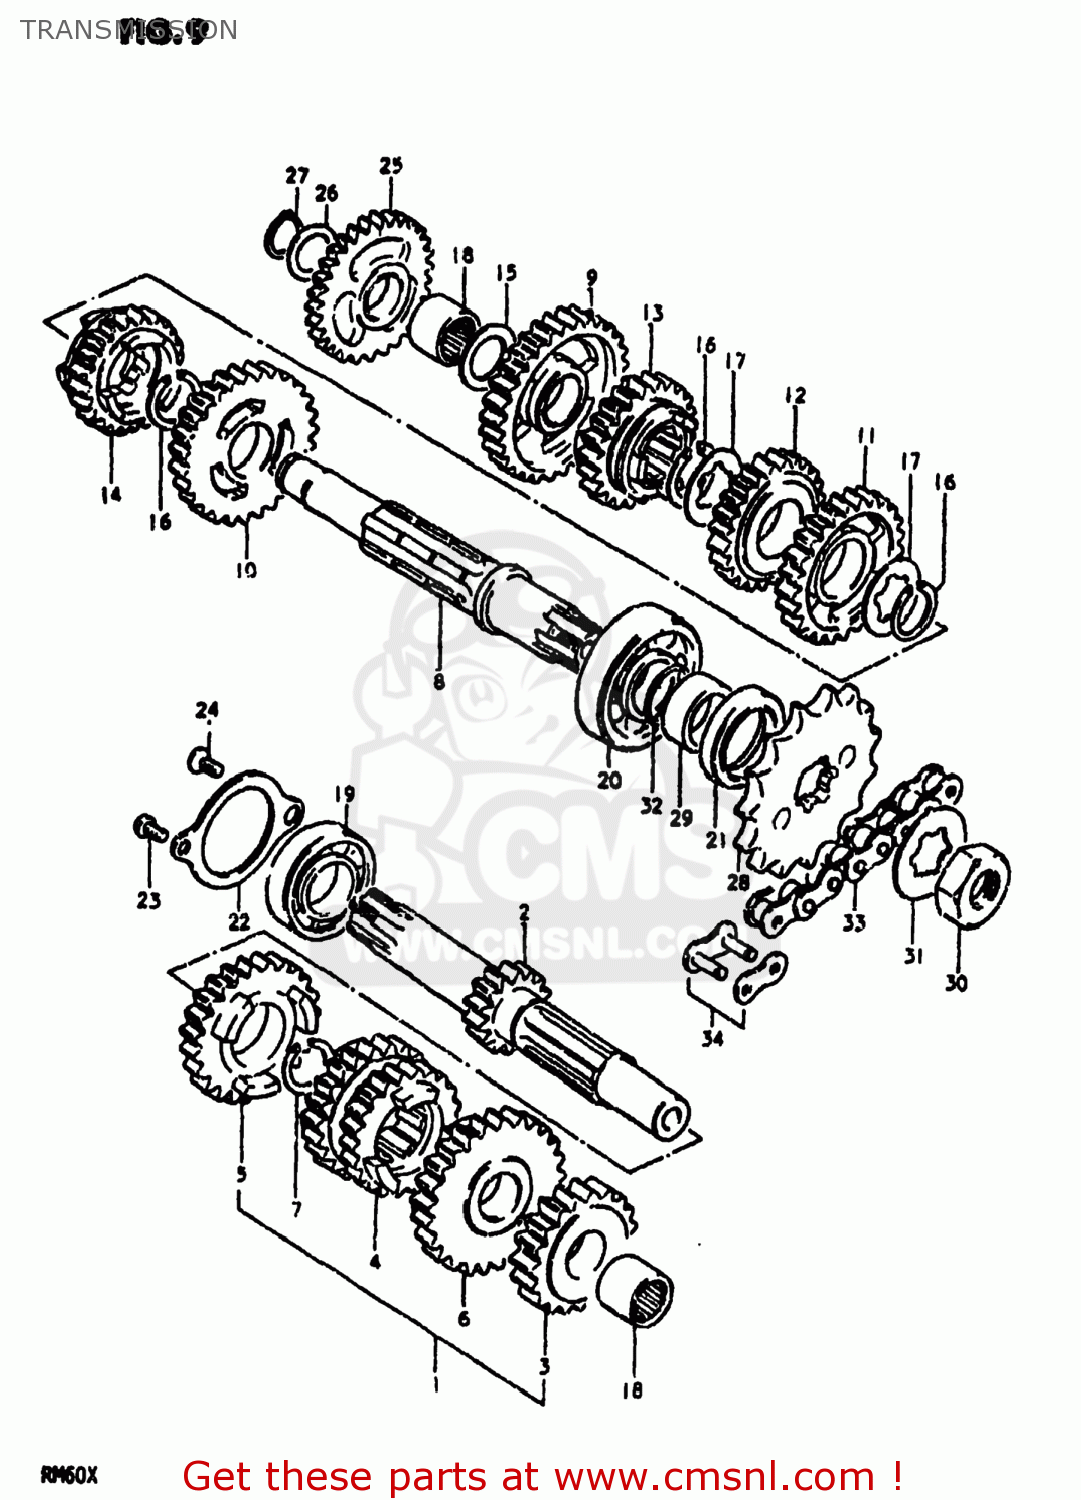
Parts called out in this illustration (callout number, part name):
1	SHAFT,COUNTER
2	SHAFT,COUNTER
3	GEAR,SECOND DRIVE
4	GEAR,THIRD/FOURTH DRIVE
5	GEAR,FIFTH DRIVE
6	GEAR,SIXTH DRIVE
7	CIRCLIP
8	SHAFT,DRIVE
9	GEAR,FIRST DRIVEN
10	GEAR,SECOND DRIVEN
11	GEAR,THIRD DRIVEN
12	GEAR,FOURTH DRIVEN
13	GEAR,4TH DRIVEN(NT:36)
14	GEAR,SIXTH DRIVEN
15	WASHER(13X24X1)
16	CIRCLIP
17	WASHER,LOCK
18	ROLLER BEARING (13X19X1
19	BEARING
20	BEARING
21	SEAL,OIL(21X35X5)
22	RETAINER,CNTR SHAFT BEARING
23	SCREW
24	SCREW
25	GEAR,KICK STARTER IDLE
26	WASHER
27	CIRCLIP
28	SPROCKET,ENGINE(NT:12)
29	SPACER (17X21X11)
30	NUT
31	WASHER,LOCK
32	O RING(D:1,ID:16.8)
33	CHAIN ASSEMBLY,DRIVE
34	JOINT ASSEMBLY,CHAIN
